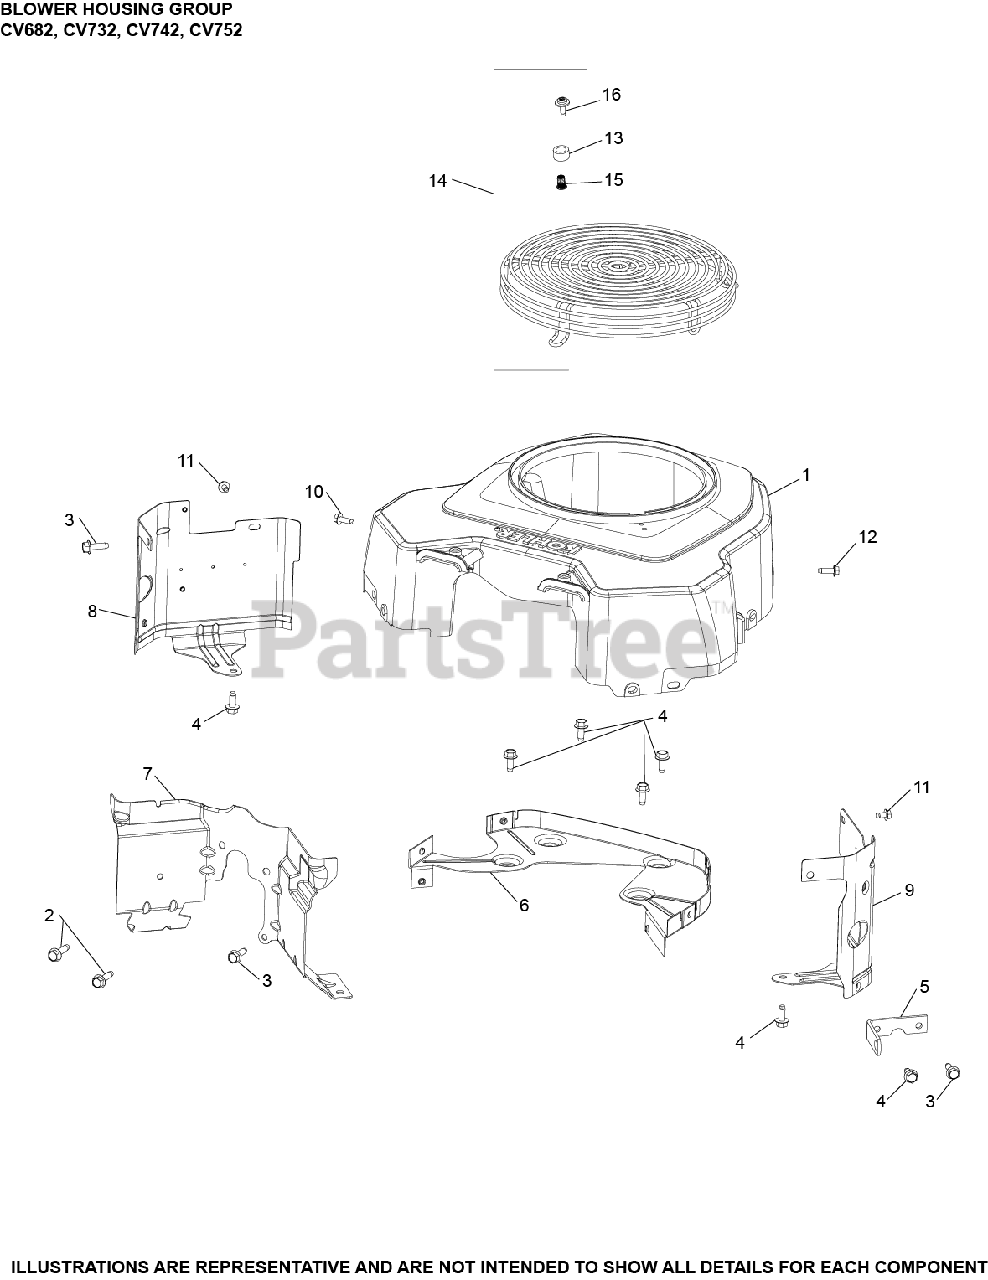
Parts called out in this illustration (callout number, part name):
1	HOUSING, BLOWER
2	SCREW, THREAD FORMING
3	SCREW, THREAD FORMING
4	SCREW, THREAD FORMING
5	STRAP, LIFT
6	KIT, BACKING PLATE
8	KIT, CYL BAFFEL #1 SIDE
9	KIT, CYL BAFFEL #2 SIDE
10	SCREW, THREAD FORMING
11	SCREW, THREAD FORMING
12	SCREW, THREAD FORMING
13	SPACER USE 25 112 30-S
15	INSERT, THREADED USE 25 332 19-S
16	SCREW, SEMS
2531404-S	GUARD, GRASS SCREEN (METAL)
